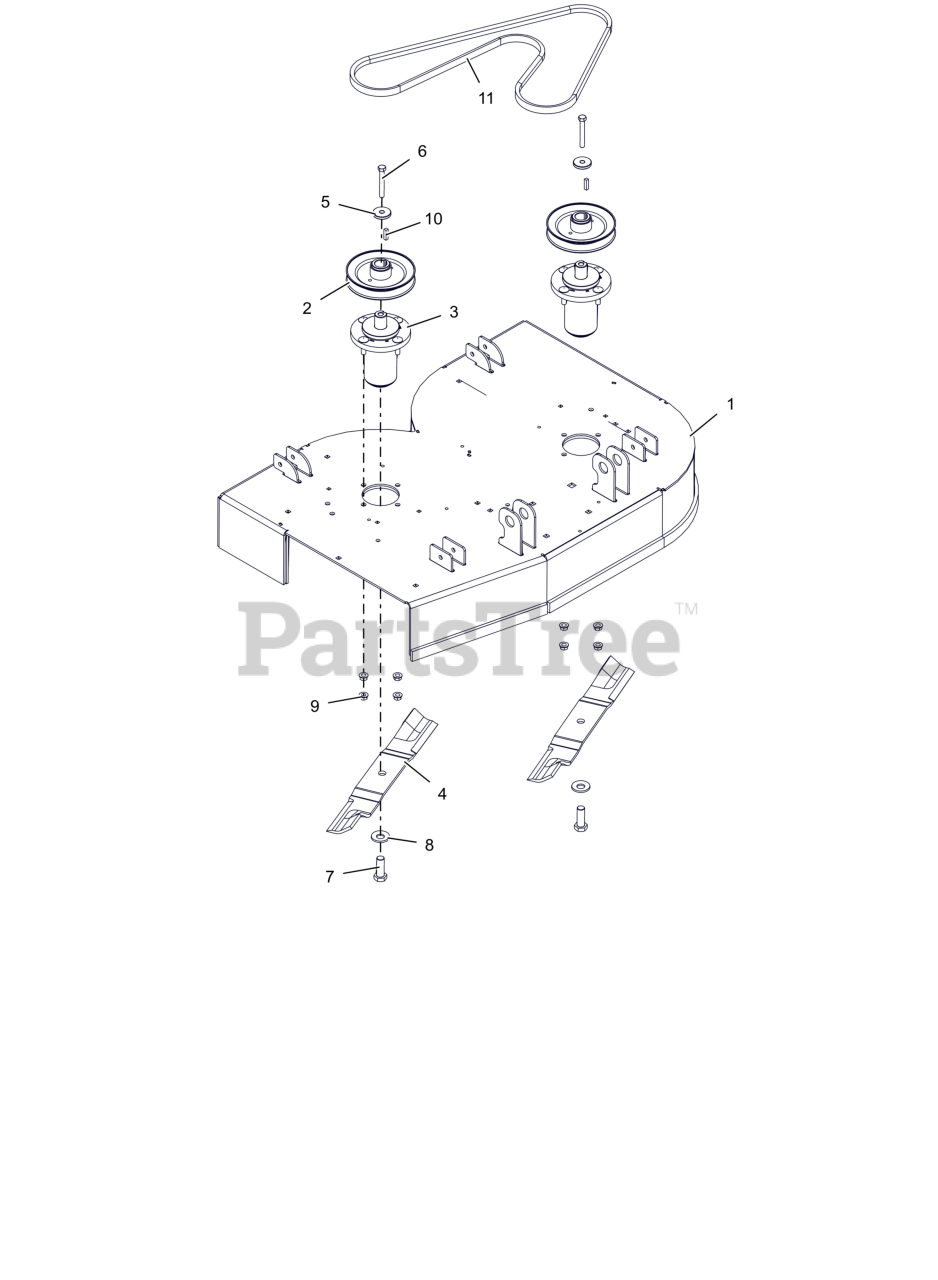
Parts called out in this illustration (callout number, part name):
1	WLDMT, 36" ARROW DECK (ORANGE)
2	PULLEY- V-1.000 ID X 5.750 OD
3	ASM, MAINT FREE ALUM SPINDLE
4	BLADE, 18.00" MOWER (HI-LIFT)
5	RETAINER, SHEAVE
6	BLT, HEX .38-16X2.75 G8 ZCC
7	BLT, HEX .62-18X1.75 G8 ZCC
8	WSHR-BLVL .669X1.535X.138
9	NUT-LK-CTR-FLG .375-16 GF ZCC
10	KEY, SQ .25X.25X1.00 RC 40-50
11	V-BELT, 5L RAW EDGE EPDM
